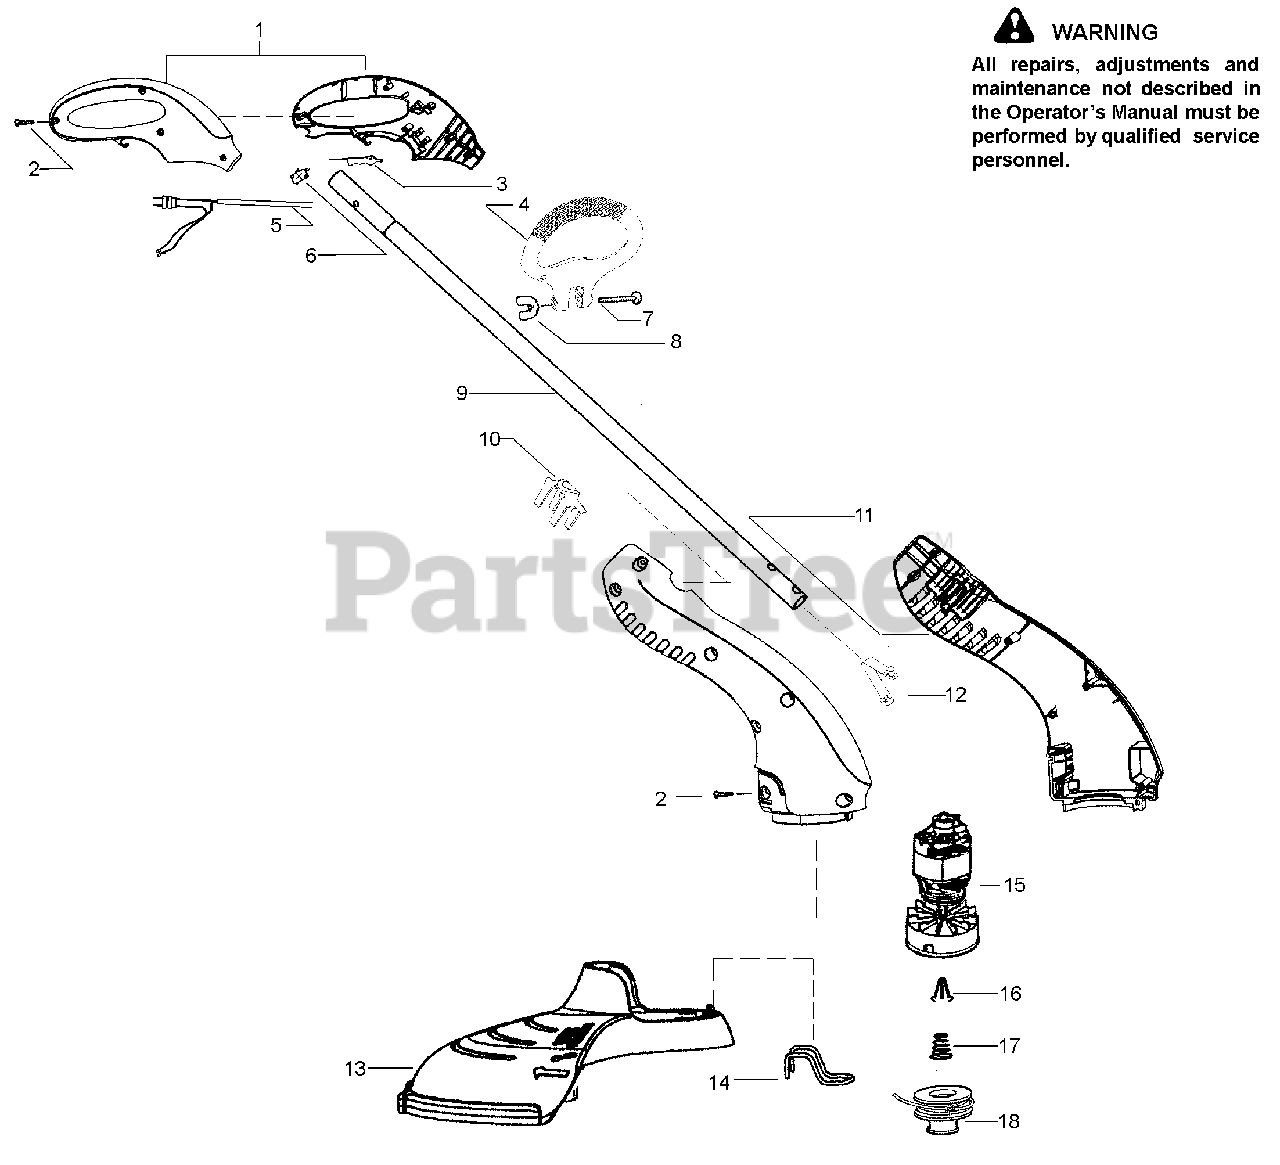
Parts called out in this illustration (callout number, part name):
1	Handle Set
4	Assist Handle
5	Wiring Harness Ass'y.
7	Bolt-Carriage
8	Wingnut
9	Tube Ass'y. w/Decal
10	Button-Push
11	Housing Set
12	Button-Snap
13	Shield Ass'y.
14	Guide - Edging
15	Assy.-Motor/Impeller
16	Retainer-Spool
17	Spring-Return
18	Assy.-W/E Spool (TNG-V)
